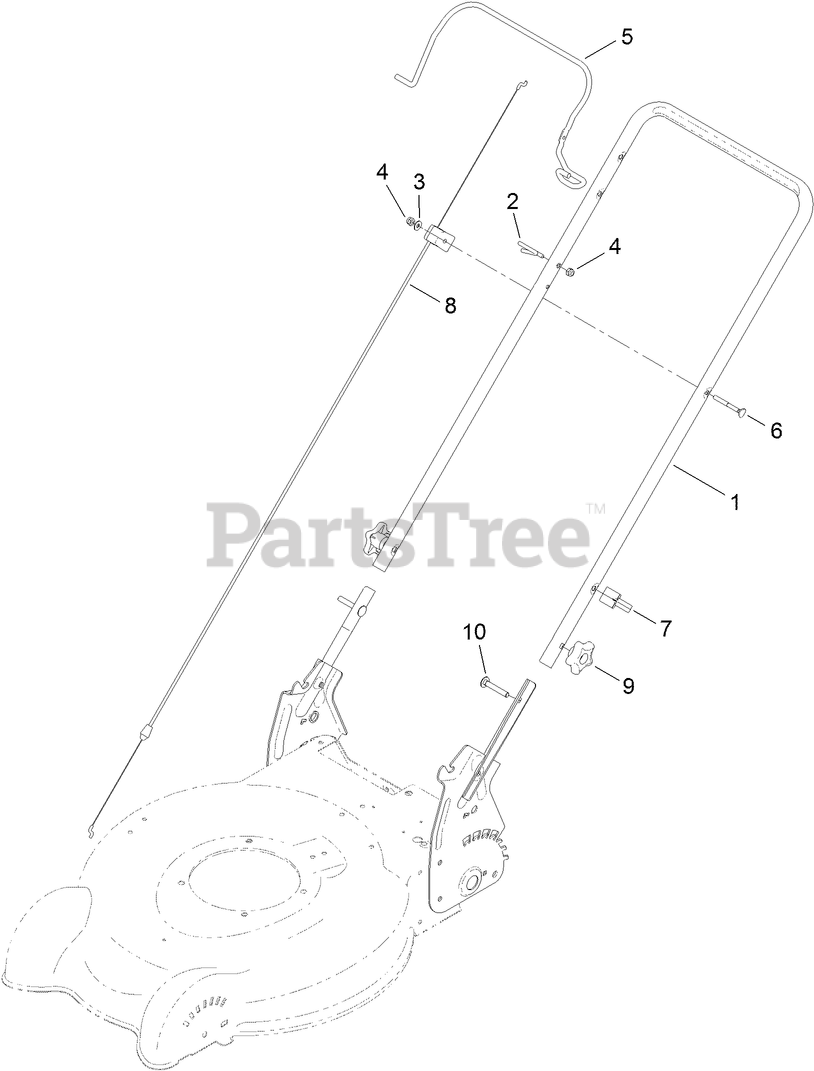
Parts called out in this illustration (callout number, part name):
1	HANDLE-UPPER
2	GUIDE-ROPE
3	WASHER-FLAT
4	NUT-LOCK, NI
6	SCREW-HANDLE
7	GUIDE-CABLE
8	CABLE-BRAKE
9	KNOB-HANDLE
10	BOLT-CARR
